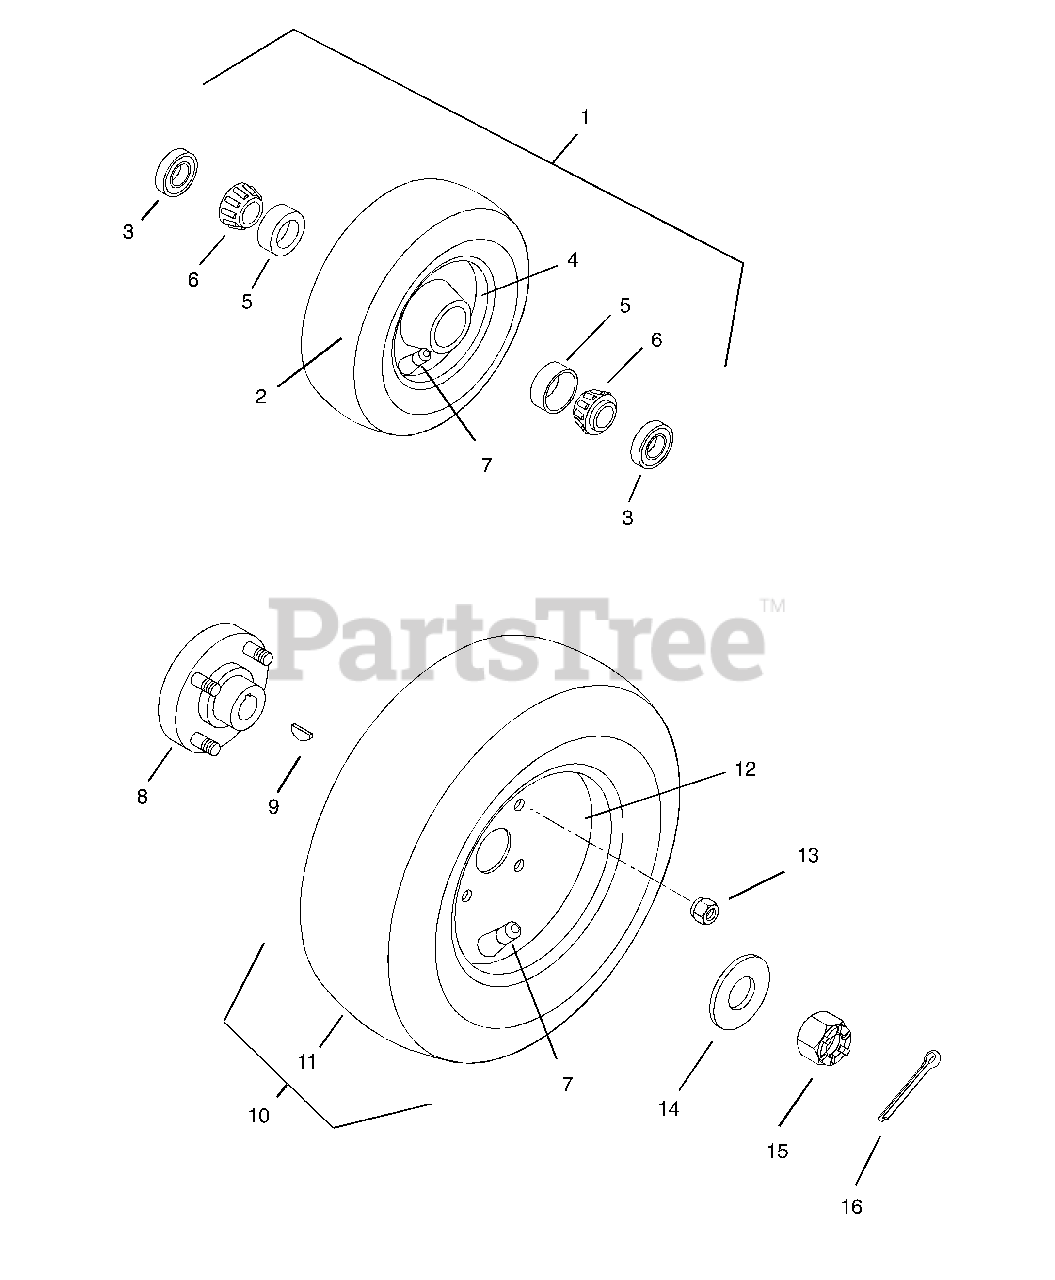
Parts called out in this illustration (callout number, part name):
1	Tire/Wheel Assembly 4.80-8
2	Tire 4.8-8
3	Seal
4	Wheel Assembly 3.75 x 8
5	Bearing-Cup 1.980 x 4.20
6	Bearing-Cone 1.0 x .58
7	Valve Stem Assembly
8	Hub w/studs
9	Key-Woodruff .25 x 1.0 x 7.00
10	Tire/Wheel Assembly 8.50-8 x 18
11	Tire 18-8.5x8
12	Wheel 8 x 7
13	Nut-Lug .50-20
14	Washer-Flat-Steel .755 x 1.375 x .062
15	Nut-Hex-Slotted .75-20
16	Pin-Cotter .12 x 1.25
